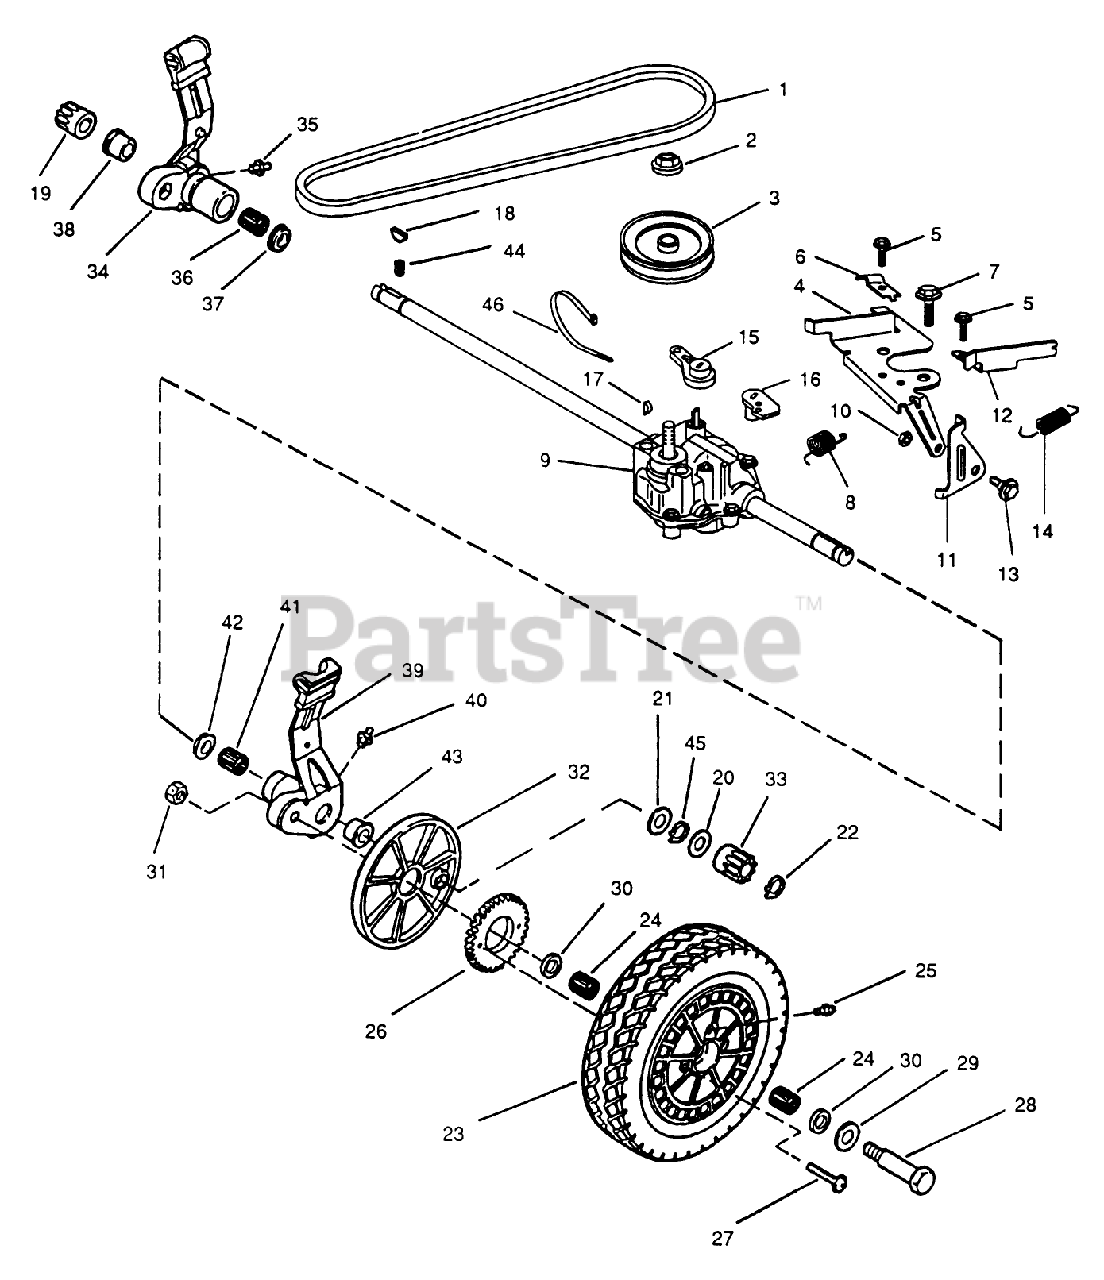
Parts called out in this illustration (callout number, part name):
3	PULLEY TRANS ADAMS
6	CLAMP-CABLE
9	TRANSMISSION ASSEM
10	LOCKNUT
16	ARM - CLUTCH
17	KEY GALGER
19	PINION(R)MET ALLEG
20	THRUST WASHER
21	WASHER-THRUST
22	RETAINING RING
25	FITTING LINCOLN
27	SCREW-TORX
28	BOLT WHEEL QUAL
31	LOCKNUT
32	COVER-WHEEL
33	PINION(L)MET ALLEG
35	**FITTING LINCOLN
37	SEAL CR IND
40	**FITTING LINCOLN
42	SEAL CR IND
45	RET RING
